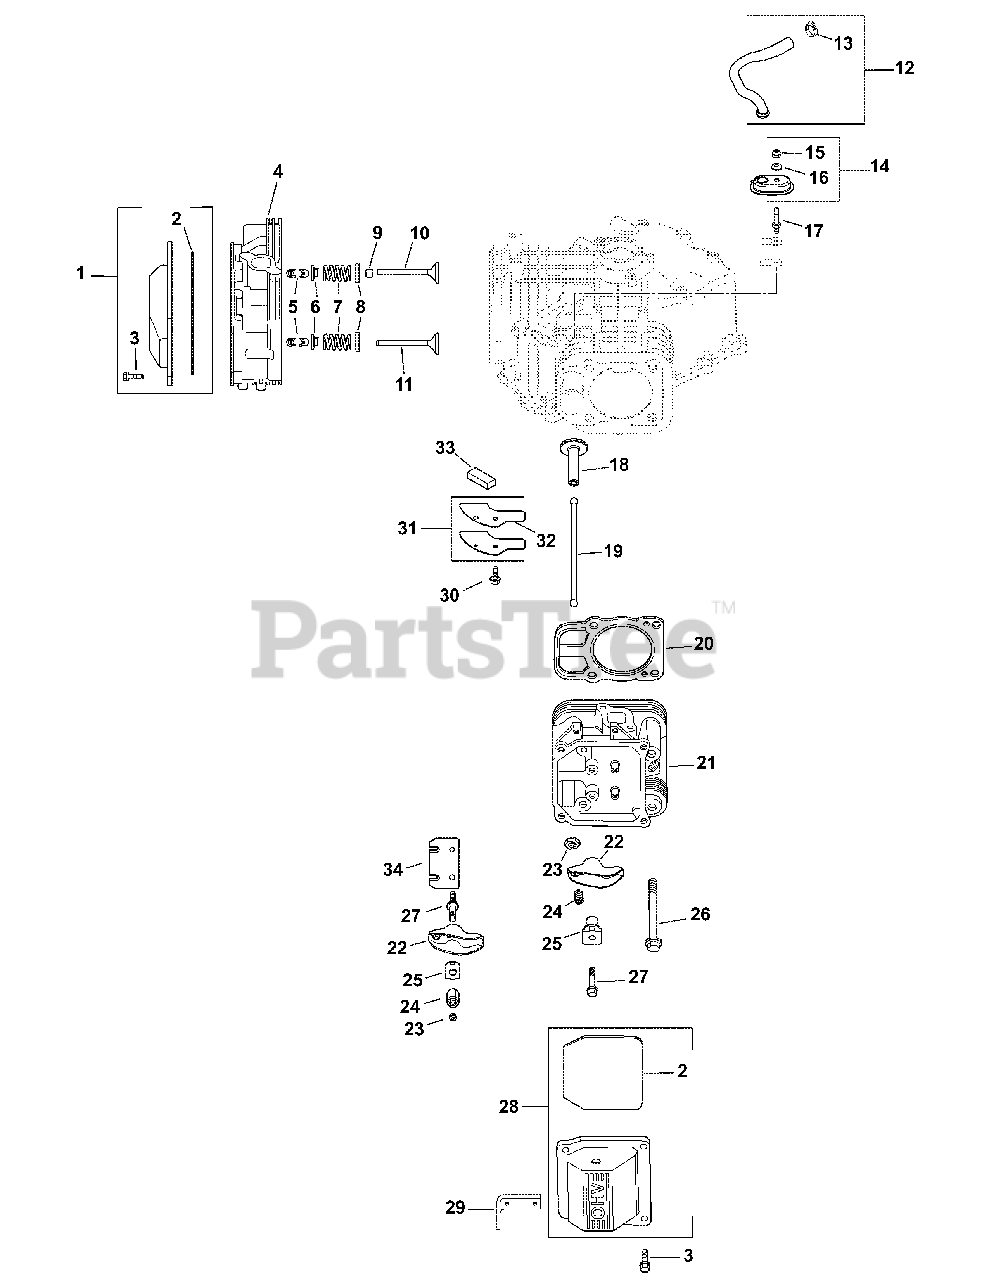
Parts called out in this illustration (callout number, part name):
1	KIT, PLAIN ROCKER COVER
2	O-RING, VALVE COVER
3	SCREW, FLG M6X1.0X30
4	KIT, #1 CYLINDER HEAD ASSY
5	KIT, RETAINER
6	CAP, VALVE SPRING
7	SPRING, VALVE
8	RETAINER, SPRING
9	SEAL, VALVE STEM
10	VALVE, INTAKE (STD)
11	VALVE, EXHAUST (STD)
12	KIT, BREATHER HOSE
13	CLAMP, HOSE
14	KIT, BREATHER HOUSING
15	NUT, LOCK M5X0.8
16	WASHER, SEALING
17	STUD, BREATHER COVER
18	KIT,TAPPET
20	KIT, CYLINDER HEAD GASKET
21	KIT, #2 CYLINDER HEAD ASSY
23	NUT, M10X0.75
24	SCREW, SET
25	PIVOT, ROCKER ARM
26	SCREW, FLG M10X1.5X90
28	KIT, BREATHER VALVE COVER
29	STRAP, LIFTING
30	SCREW, FLG THD FRM M6X1.0X16
31	KIT, BREATHER COVER
32	GASKET, BREATHER COVER
33	FILTER, BREATHER
